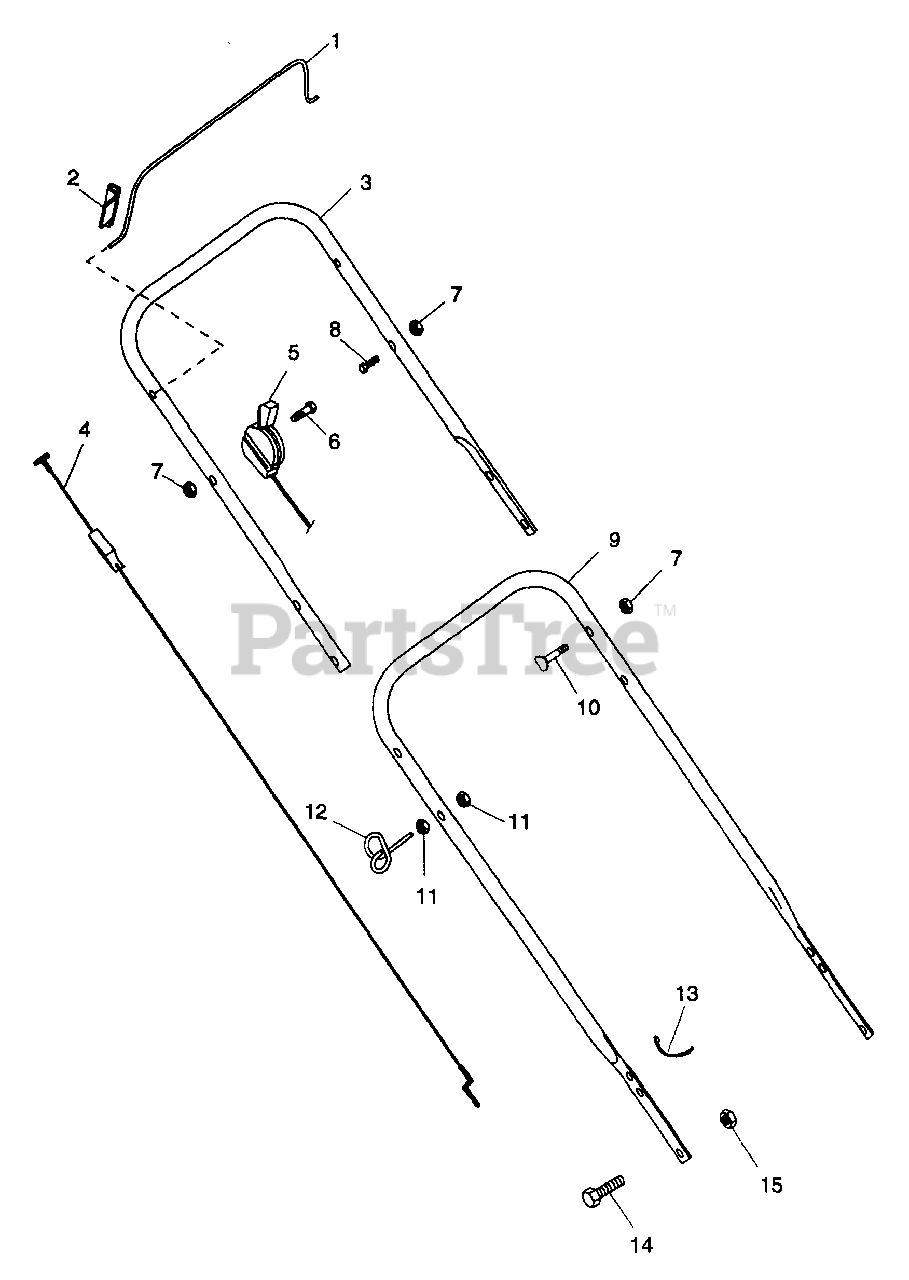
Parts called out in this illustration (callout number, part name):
2	BAIL STOP
3	UPPER HANDLEBAR
4	CABLE-ENGINE CONTROL
5	CABLE-THROTTLE
6	BLT-HEX .25-20X1.75 PL GR2
7	NUT-LK TOP .250-20 PL
8	BLT-HEX .25-20X1.25 PL GR5
9	LOWER HANDLEBAR
10	BLT-CRVD-HD .25-20X.25 PL
11	NUT-LK-FLG .250-20 PL
12	SUPPORT
13	CABLE TIE LG 5-1/2
14	BLT-HEX .31-18X.63 PL GR 2
15	NUT-FLG. .312-18 PL
